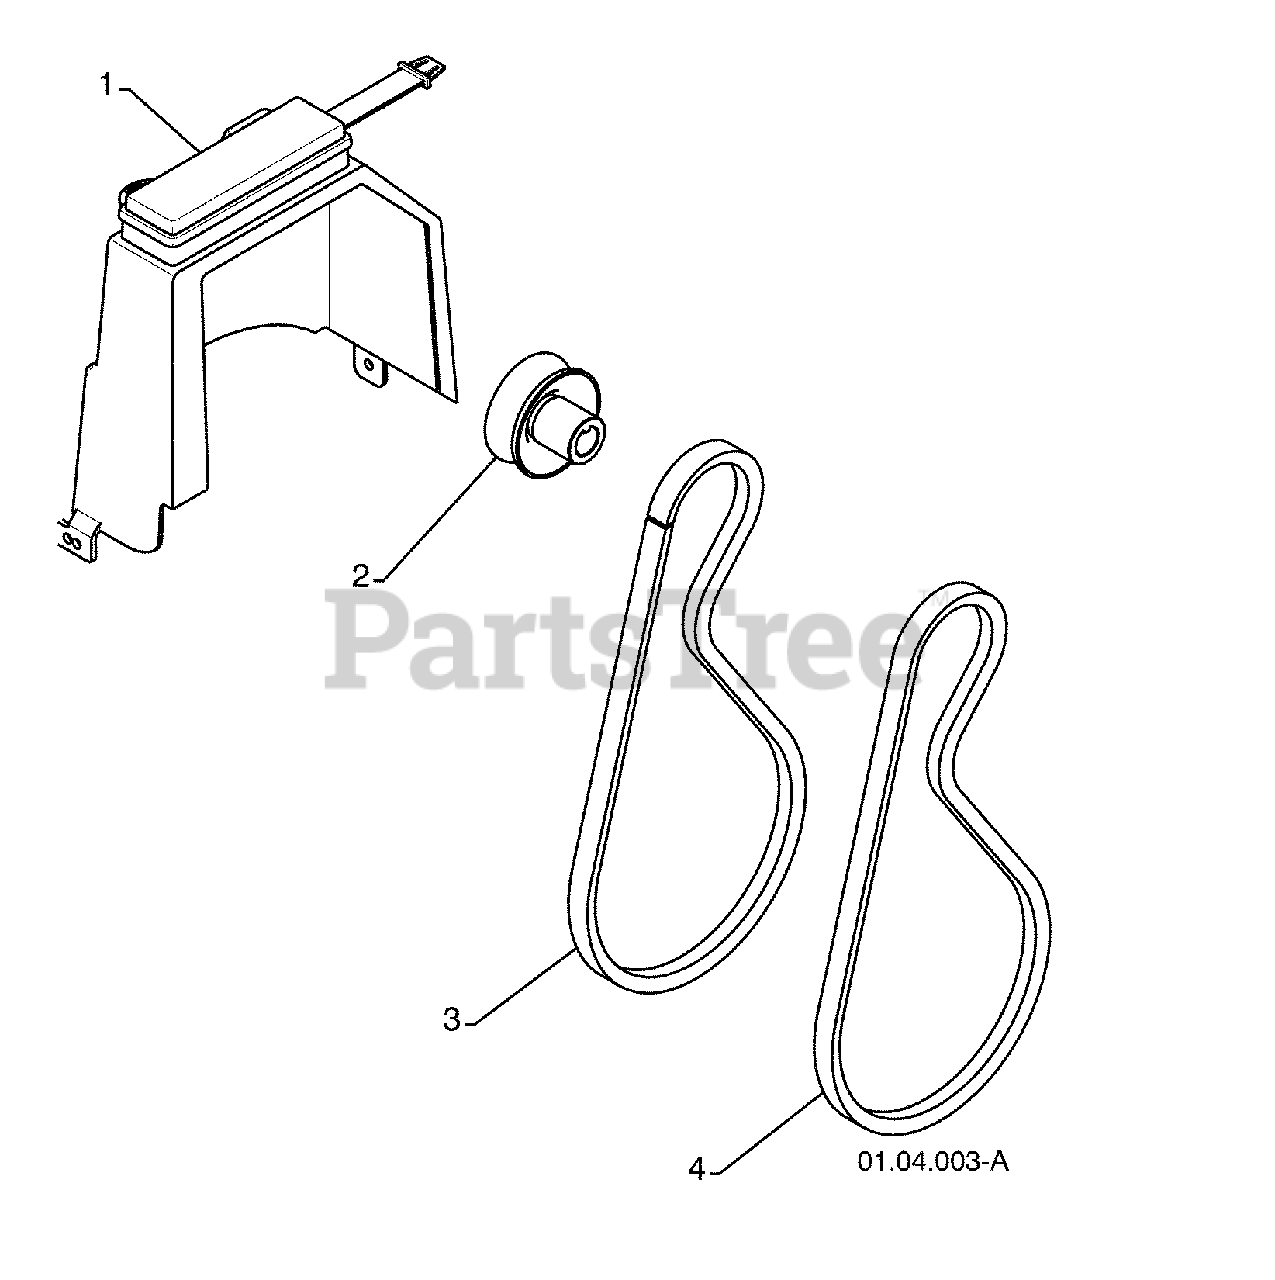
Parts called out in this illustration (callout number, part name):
1	COVER ASSEMBLY
2	PULLEY
3	TRACTION BELT
4	IMPELLER BELT
